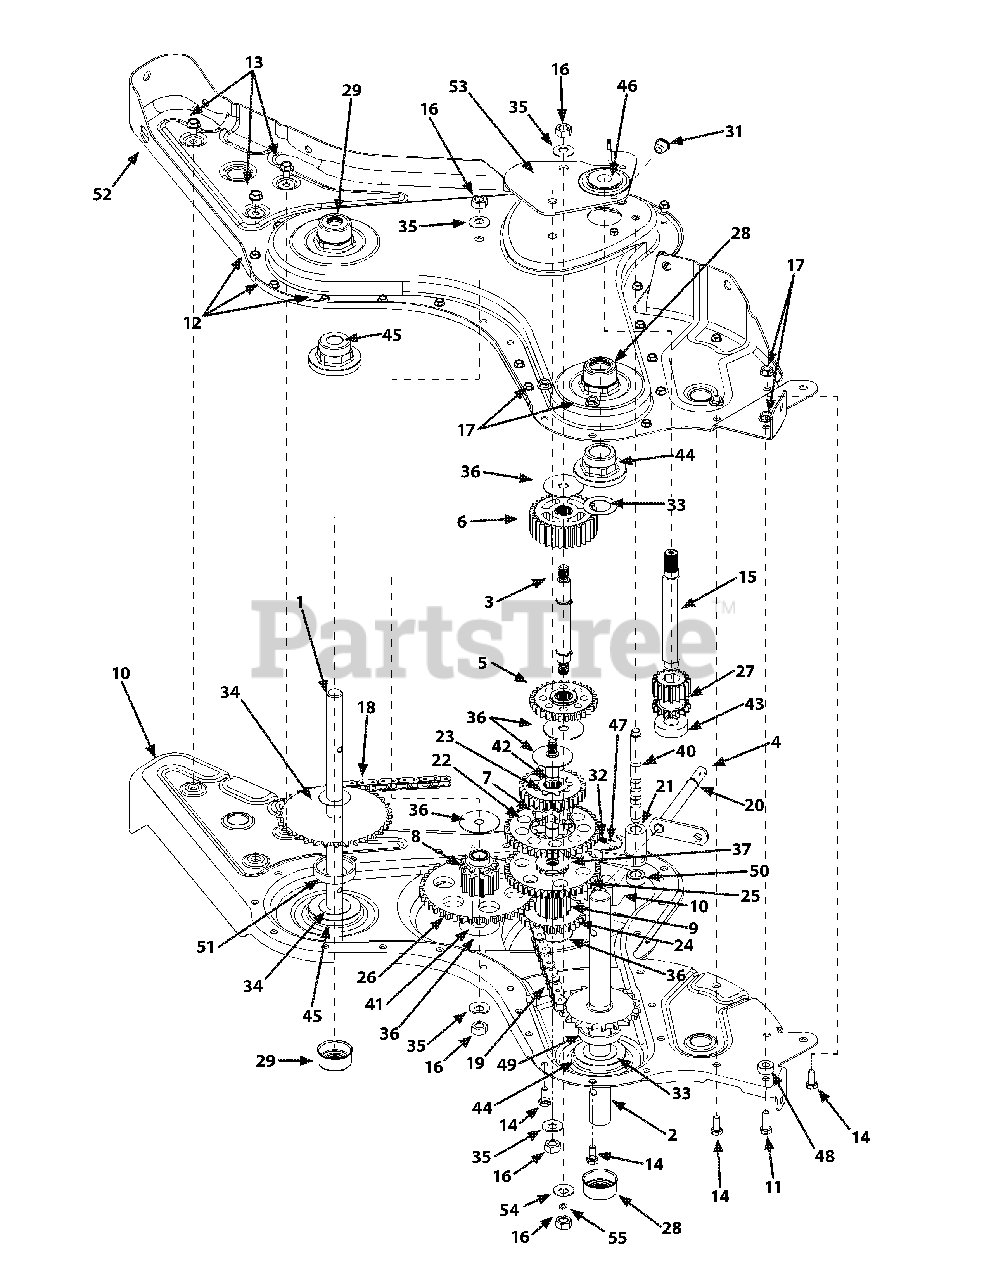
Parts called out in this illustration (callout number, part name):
1	Wheel Shaft Assembly: 33T
2	Tine Shaft Assembly: 18T
3	Jack Shaft Assembly
4	Input Shaft Assembly
5	Reverse Idler Gear Assembly: 30T
6	Tine Idler Gear Assembly: 30T
7	Tine Input Sprocket Assembly: 9T
8	Wheel Inp. Sprocket Assembly: 10T
9	Gear Assembly:11T
10	R.H. Housing Assembly
11	Hex Bolt,5/16-18 x 1" Lg.
12	Hex S-Tap Screw, 1/4- 20 x.5"
13	Hex S-Tap Screw, 5/16-18x.625"
14	Hex Bolt, 5/16-18 x.75"
15	Input Shaft
16	Hex Nut, 7/16-20
17	Flange Nut, 5/16-18
18	#420 Chain,1/2 Pitch x 50 Links
19	#50 Chain, 5/8 Pitch x 54 Links
20	Snap Ring
21	Shifting Fork
22	Spur Gear, 44T
23	Spur Gear, 30T
24	Spur Gear, 30T
25	Spur Gear, 44T
26	Spur Gear, 44T
27	Spur Gear, 16T
28	Seal 1.0 Shaft
29	Seal .75 Shaft
31	Taper Cap Ring
32	Compression Spring, .50" Leg.
33	Thrust Washer, 1.03" I.D. X. 1.62"
34	Fl-Washer, .76" I.D. x 1.5" O.D.
35	Bell-Washer, .45" I.D. x 1.0"
36	Thrust Washer, .445 x 1.92 x .060
37	Fl-Washer, .635" I.D. x 1.59 O.D.
40	Detent Shaft, 1/2" Dia.
41	Jack Shaft, .625 x 2.385
42	Jack Shaft, .625 x 5.0
43	Ball Bearing
44	Flange Bearing, 1.0 x 2.5 x 1.38
45	Flange Bearing, .75 x 2.5 x 1.38
46	Ball Bearing, .6692 x 5745 x .466
47	Detent Ball, .250
48	Spacer, .315
49	Spacer, 1.0 I.D x 2.0 O.D. x .440
50	Spacer, .505 I.D. x .88 O.D. x .440
51	Spacer, .75 x 2.0 x .50
52	L.H. Chain Case Assembly
53	Gear Positioner Bracket
54	Flat Washer, .474 x .879 x .064
55	Lock Washer, 7/16
